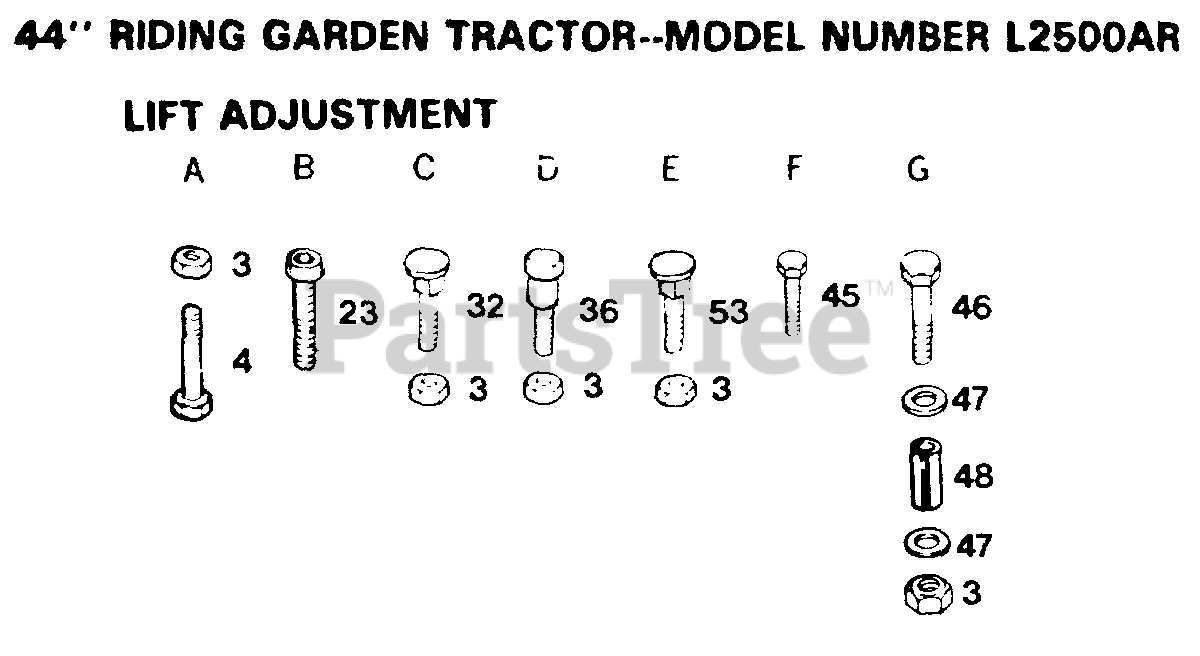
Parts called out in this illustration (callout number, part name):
23	SCREW LT
32	BOLT
36	"BOLT, SHOULDER LT"
45	SCREW
47	WASHER GT
